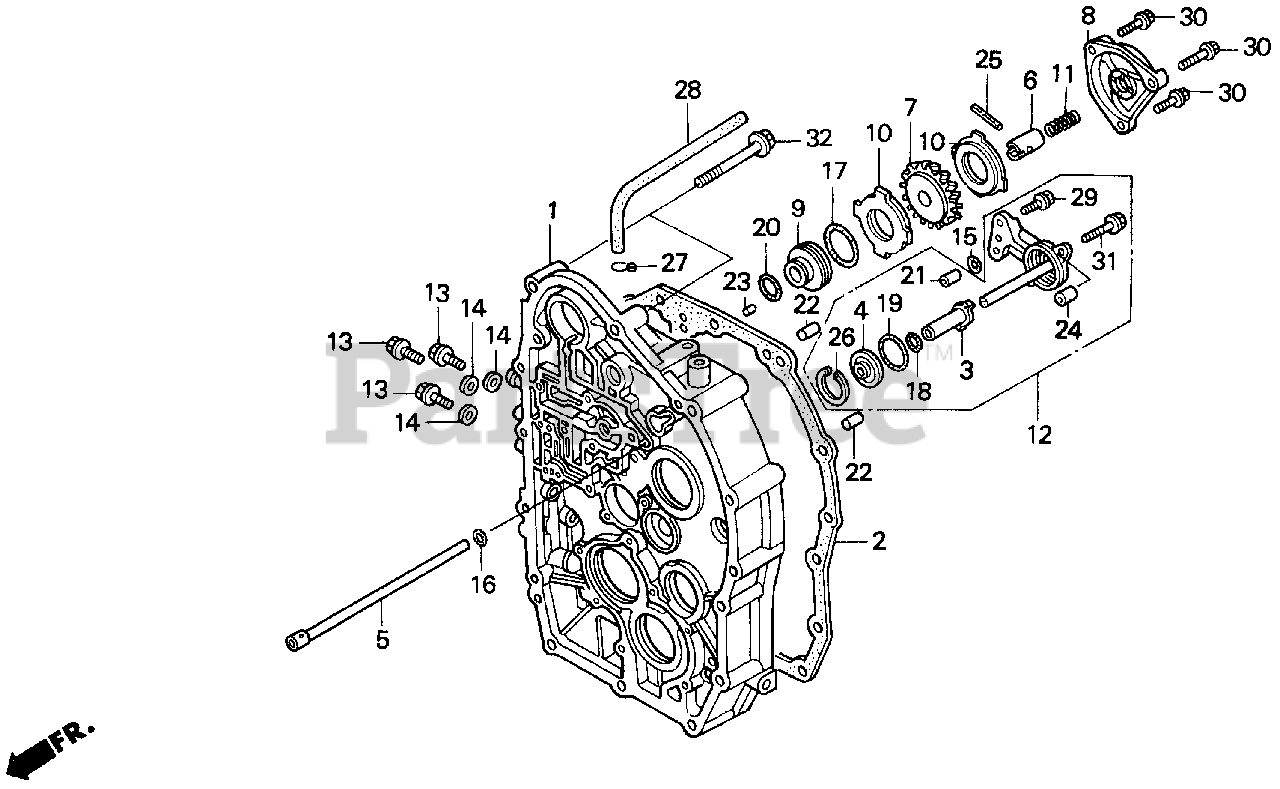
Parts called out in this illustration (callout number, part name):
1	CASE, CONTROL
2	GASKET, CONTROL CASE
3	PIPE A, FEED
4	GUIDE A, FEED PIPE
5	PIPE, OIL SUPPLY
6	SHAFT, NEUTRAL BRAKE
7	GEAR, NEUTRAL BRAKE (19T)
8	COVER, NEUTRAL BRAKE
9	PISTON, NEUTRAL BRAKE
10	PLATE, NEUTRAL BRAKE
11	SPRING, NEUTRAL BRAKE
12	HOLDER C ASSY., FEED PIPE
13	BOLT, SEALING (8MM)
14	WASHER (8MM)
15	O-RING (7.5X1.5)
16	O-RING (5.8X1.9)
17	O-RING (38.5X1.8)
18	O-RING (8.5X1.9) (NOK)
19	O-RING (31X1.7) (ARAI)
20	O-RING (26X1.5) (NOK)
21	PIN A, DOWEL (6X10)
22	PIN, DOWEL (8X14)
23	PIN C, DOWEL (4X6.5)
24	PIN A, DOWEL (8X14)
25	PIN, SPRING (3X32)
26	CIRCLIP (INNER) (32MM)
27	CLIP, TUBE (B10)
28	BULK HOSE, VACUUM (5.5X3000) (5.3X300)
29	BOLT, FLANGE (6X18)
30	BOLT, FLANGE (6X22)
31	BOLT, FLANGE (6X28)
32	BOLT, FLANGE (10X50)
